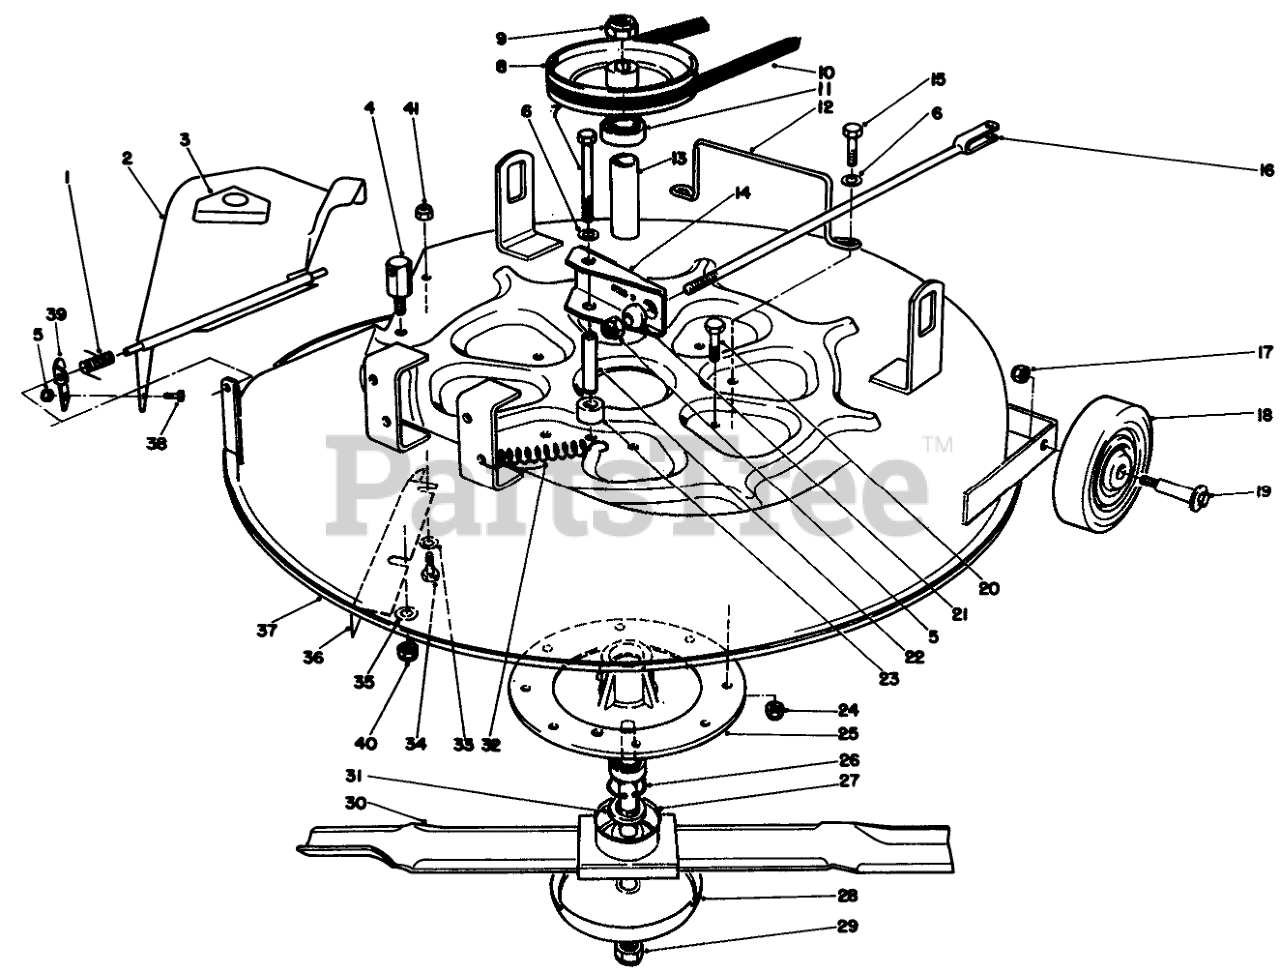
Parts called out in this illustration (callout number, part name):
1	SPRING
2	Deflector (Incl. Ref. #3)
3	DECAL-DANGER
4	POST-PIVOT
5	NUT-LOCK, NI
6	WASHER-PLAIN
7	SCREW-HH
8	DECK PULLEY
9	NUT-LOCK, NI
10	V-Belt
11	BEARING-BALL
12	DECK BELT GUIDE
13	SPACER-BEARING
14	DECK BRAKE ASSEMBLY
15	SCREW-HH
16	DECK BRAKE ROD WA
17	NUT-LOCK, NI
18	WHEEL-DECK
19	BOLT-WHEEL
20	SCREW-HH
21	BALL-SWIVEL, STOP
22	POST-BRAKE MTG
23	SPACER-DECK BRAKE
24	NUT-LOCK, NI
25	CASTING-SPINDLE
26	RING-RETAINING
27	Shaft-Spindle
28	Cup
30	Blade
31	SPINDLE SPACER
32	SPRING-EXTENSION
33	WASHER-FLAT
34	SCREW-HH
35	WASHER-FLAT
36	Baffle
37	Deck
38	SCREW-HH
39	Bracket-Detector
40	NUT-LOCK, NI
41	NUT-HEX
